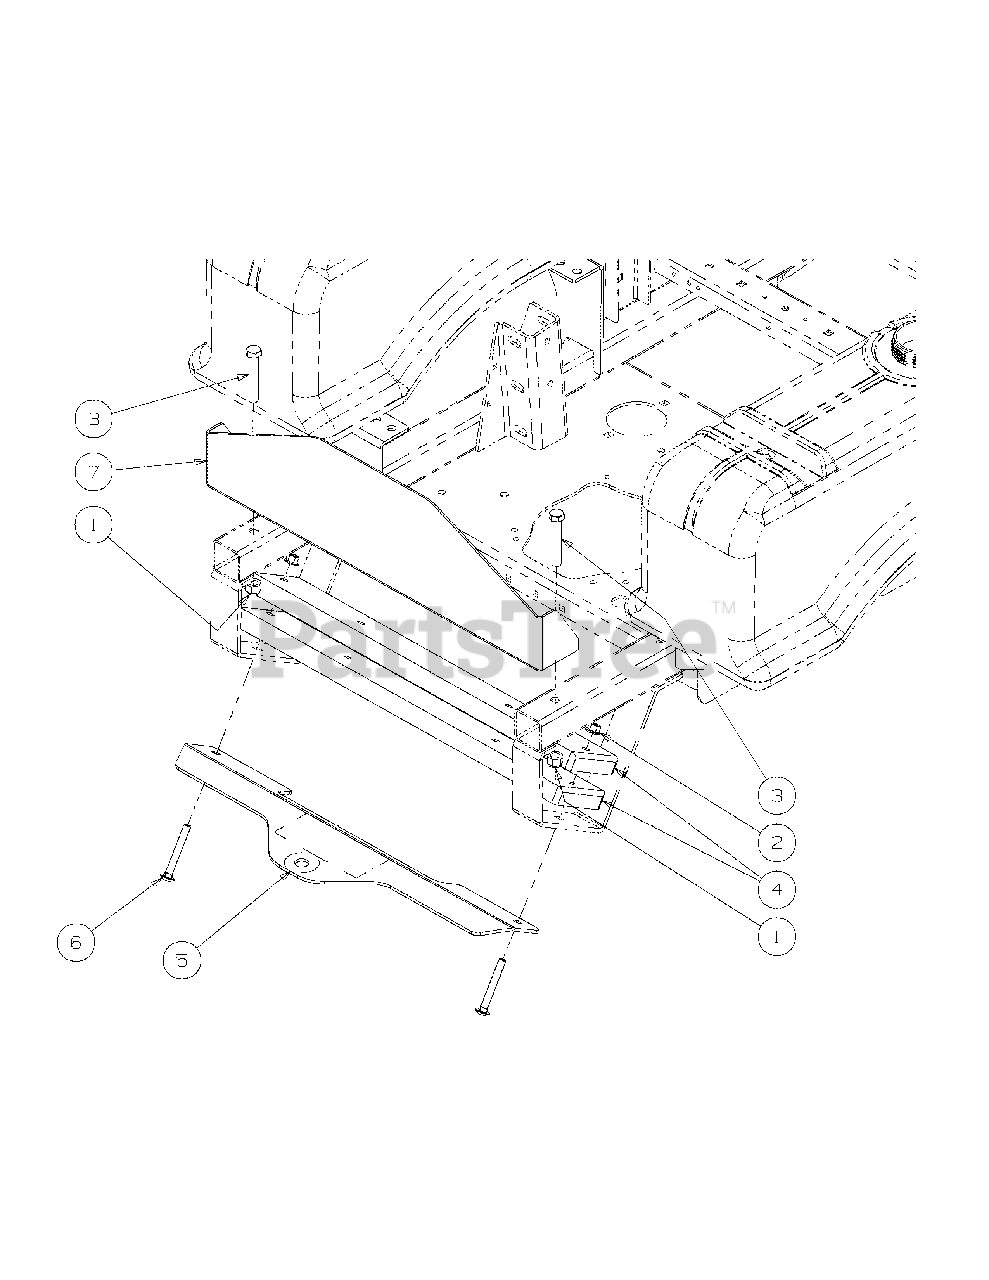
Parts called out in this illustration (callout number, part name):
1	Hex Nut, 1/2-13, Insert Lock
2	Nut, Hex 3/8-16 Flange Lock
3	HHCS, 1/2-13, 3.00
4	Bar, Weight
5	Hitch Bracket
6	Carriage Bolt, 3/8-16 x 3.00
7	Rear Bumper
